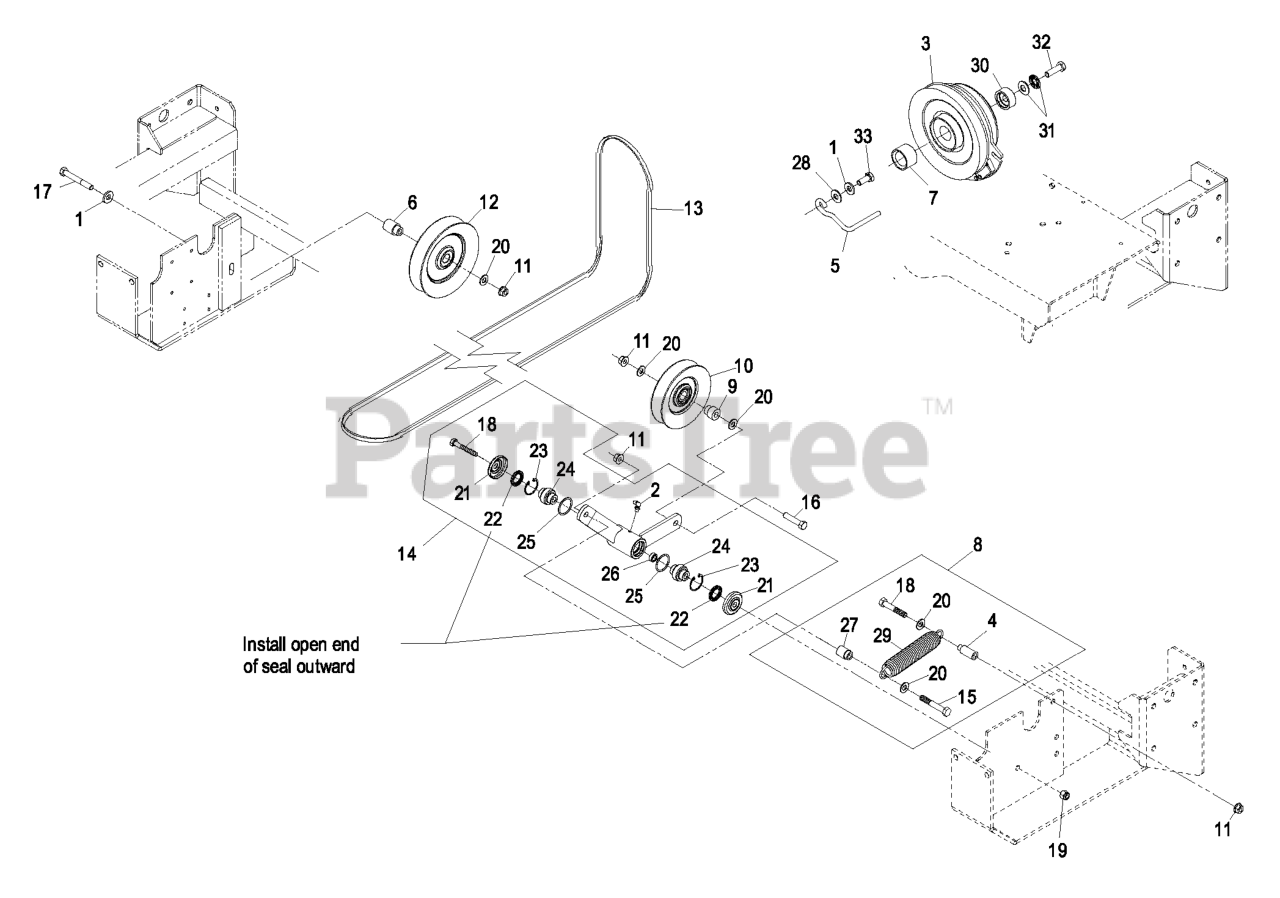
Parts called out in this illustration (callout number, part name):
1	WASHER-BELLEVILLE
2	FITTING-GREASE, 90 DEG
4	SPACER,SPRING MOUNT
5	ROD-BELT
6	BUSHING-IDLER
7	SPACER-CLUTCH
8	KIT,MULE DRIVE SPRING
9	BUSHING-IDLER
10	PULLEY-IDLER
11	NUT-HHF, WHIZ
12	PULLEY-IDLER
13	BELT-V B 118.75
14	KIT,MULE IDLER LZ
15	SCREW-HH
16	SCREW-HH
17	SCREW-HH
18	SCREW-HH
19	NUT-LOCK, NI
20	WASHER-FLAT
21	GUARD-TOP
22	SEAL-LIP, SINGLE
23	RING-SNAP
24	BEARING-SPHERICAL
27	BUSHING-IDLER
28	WASHER-FLAT
30	KEEPER-CLUTCH
31	WASHER-SPRING
32	SCREW-HH
33	SCREW-HH
